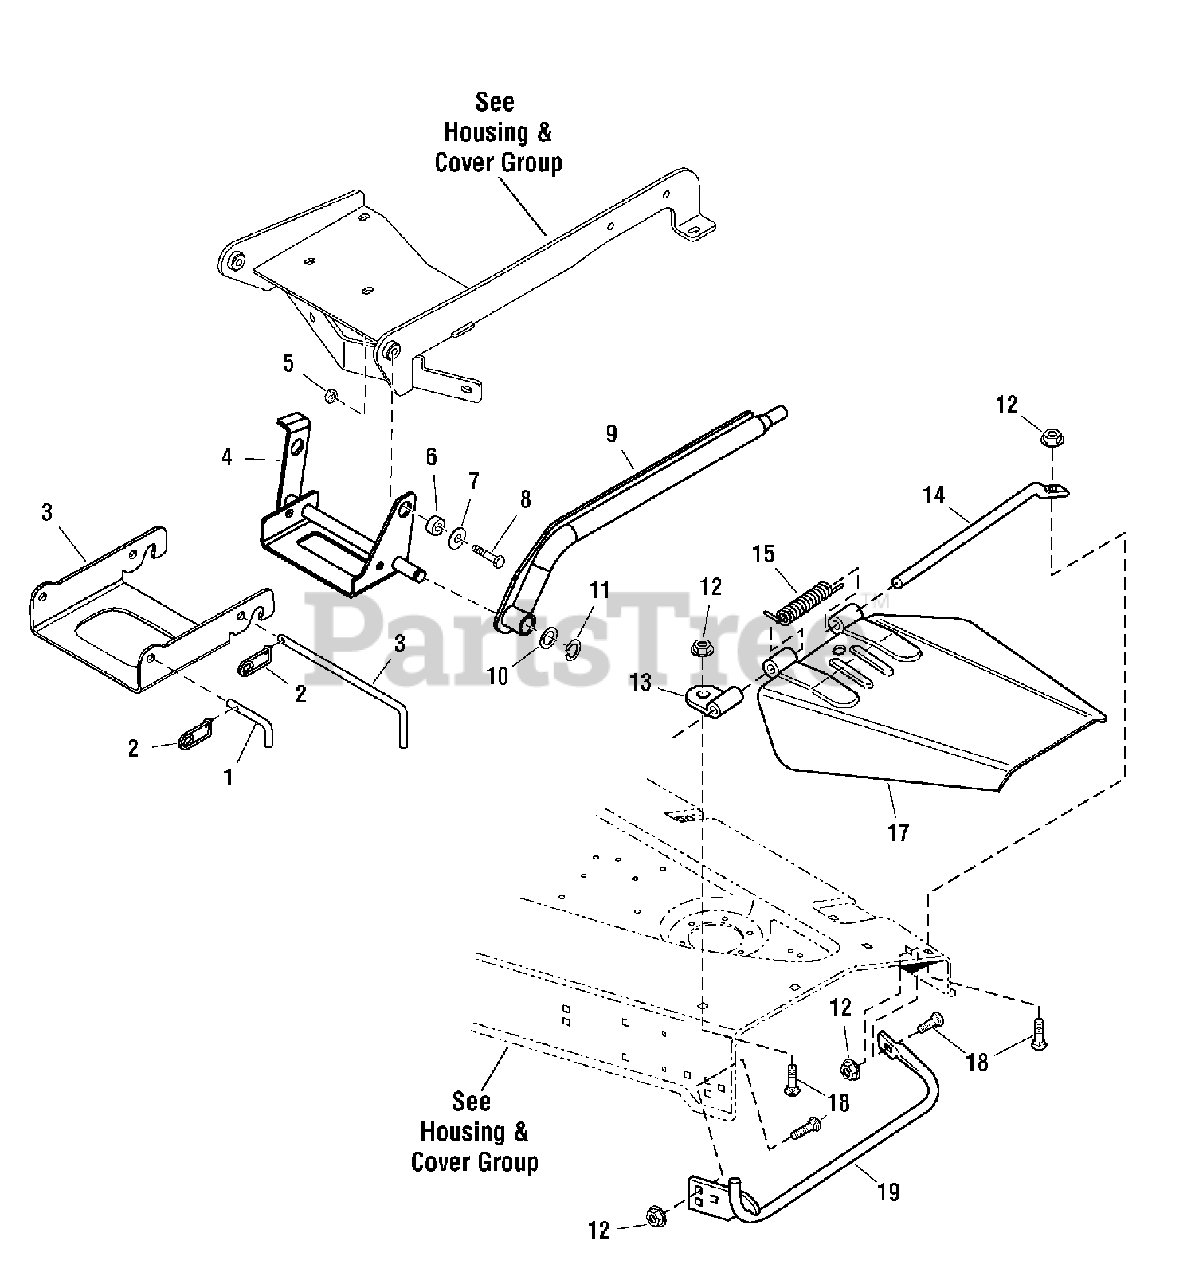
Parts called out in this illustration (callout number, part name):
2	PIN, Retainer, Spring
4	HITCH ASSEMBLY
5	NUT, Hex Top Flange Lock, 3/8-16
7	WASHER, 3/8
8	CAPSCREW, Hex Head, 3/8-16 x 1-3/4, Black
9	ARM ASSEMBLY
10	WASHER, 1, Black
11	RING, Retaining, External, 1, Black
12	NUT, Hex Flange Lock ESNA, 3/8-16, Black
13	BRACKET
15	SPRING, Torsion
17	DEFLECTOR & HINGE ASSEMBLY, Orange
17	DEFLECTOR & HINGE ASSEMBLY, Red
18	CARRIAGE BOLT, 3/8-16 x 1, Black
19	STONE GUARD & BRACKET ASSEMBLY
